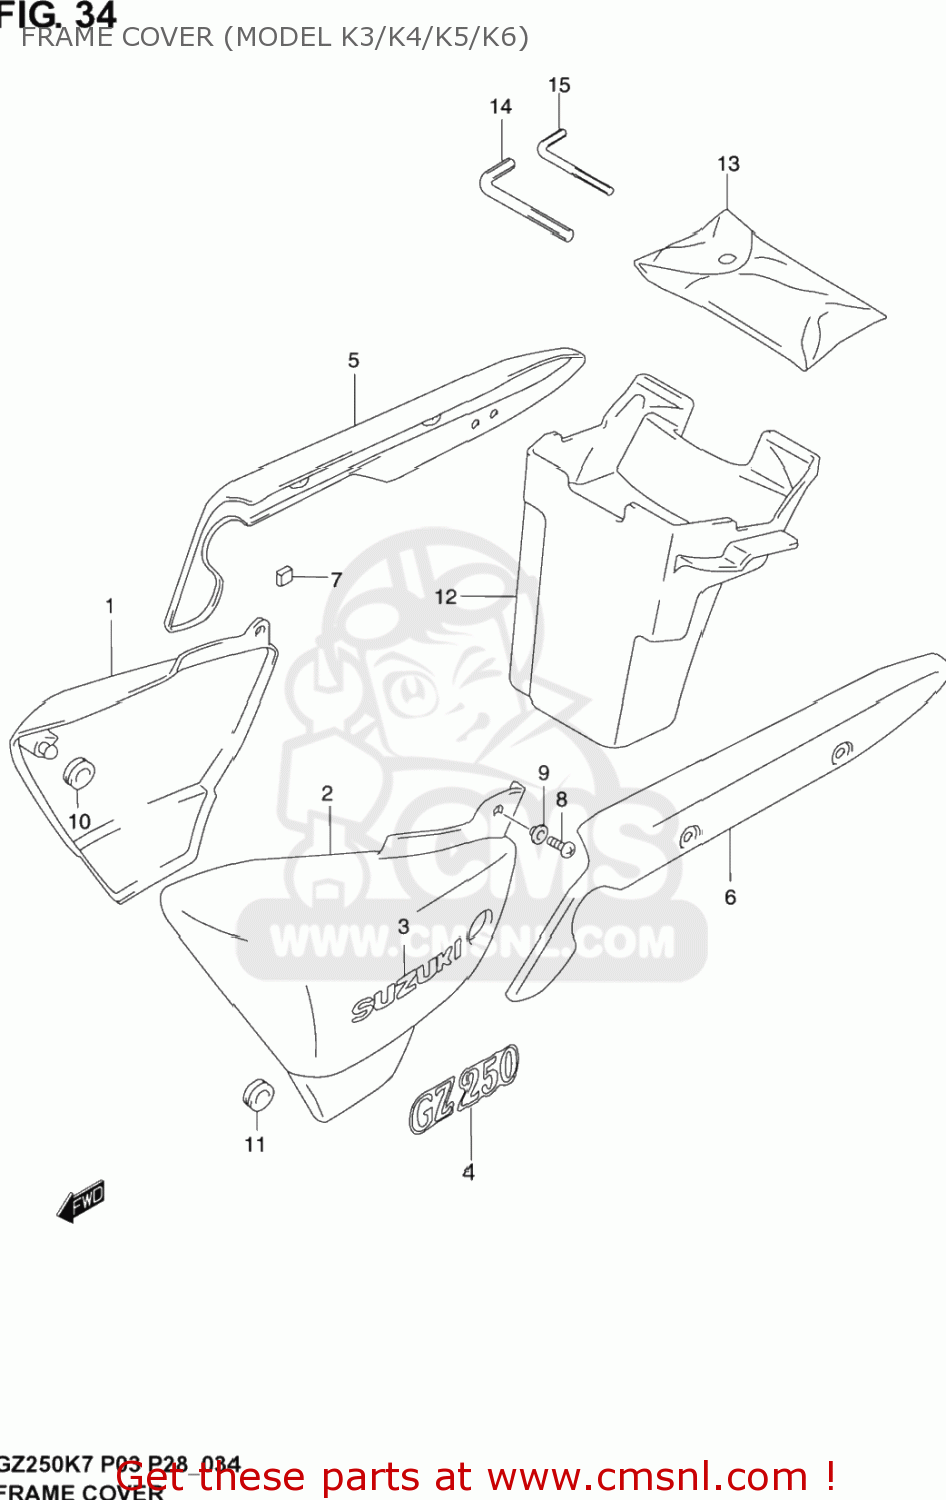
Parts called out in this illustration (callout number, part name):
1	COVER,FRAME,R(BLACK)
2	COVER,FRAME,L(BLACK)
3	EMBLEM, FRAME COVER
4	EMBLEM GZ125/K
5	COVER, FRAME REAR RH
6	COVER, FRAME REAR LH
7	CUSHION
8	SCREW 6X12
9	WASHER
10	CUSHION
11	CUSHION
12	BODY, LUGGAGE BOX
13	TOOL ASSY
14	SPANNER,HEXAGON(6)
15	SPANNER,HEXAGON(4)
